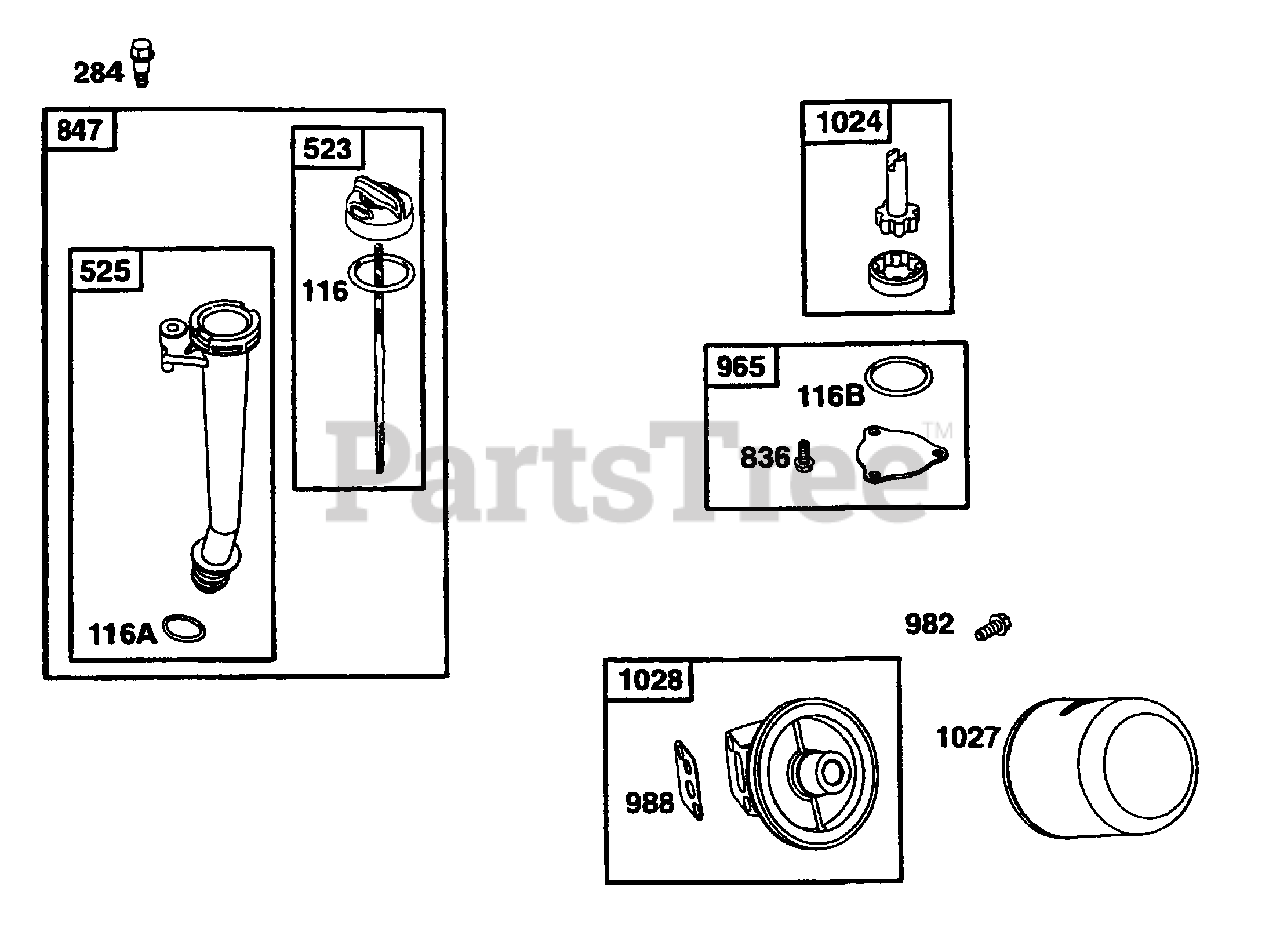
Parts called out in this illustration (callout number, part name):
116	O-Ring Seal
116A	O-Ring Seal
116B	O-Ring Seal
284	Shoulder Screw
525	Oil Fill Tube
836	Hex Screw
847	Dipstick Tube Assembly
965	Pump Cover
988	Oil Adapter Gasket
1027	Oil Filter
1028	Oil Fill Adapter
